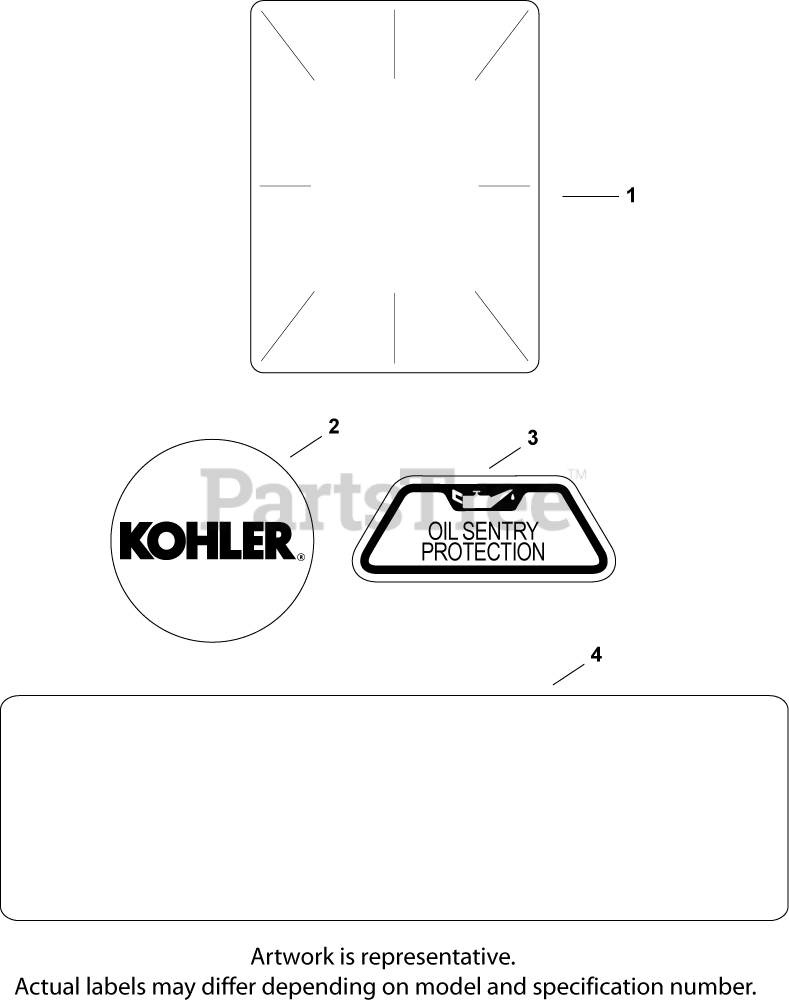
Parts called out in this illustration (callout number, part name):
1	DECAL, CLEAR LAMINATE USE 25 113 70-S
2	LABEL, (ROUND KOHLER GOLD)-USE 24 113 18
3	DECAL, OIL SENTRY - (#DSC)
4	DECAL, 25 HP
